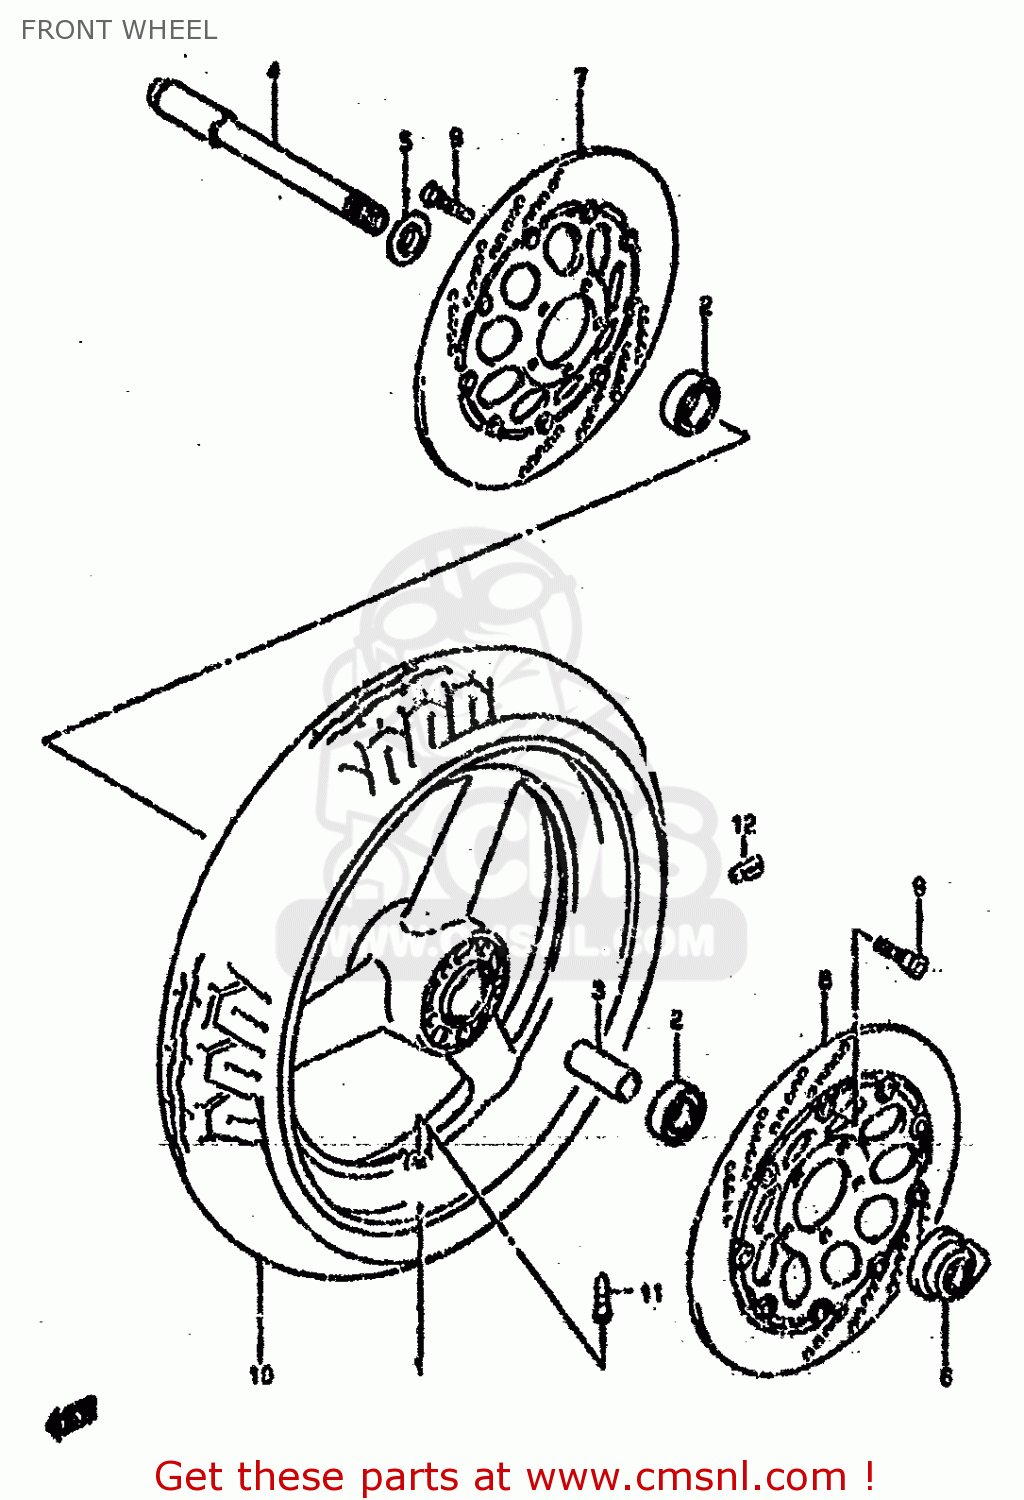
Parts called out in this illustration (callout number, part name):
1	WHEEL,FRONT
2	BEARING
3	SPACER(20.8X27.2X74)
4	AXLE,FR
5	SPACER,FR HUB BEARING,R
6	BOX ASSY,SPEEDOMETER GEAR
7	DISC,FR BRAKE,R
8	DISC,FR BRAKE,L
9	BOLT 8X33
10	TIRE,FRONT 120/70ZR17 D20
11	VALVE ASSEMBLY,WHEEL,TR412
12	BALANCER,WHEEL
